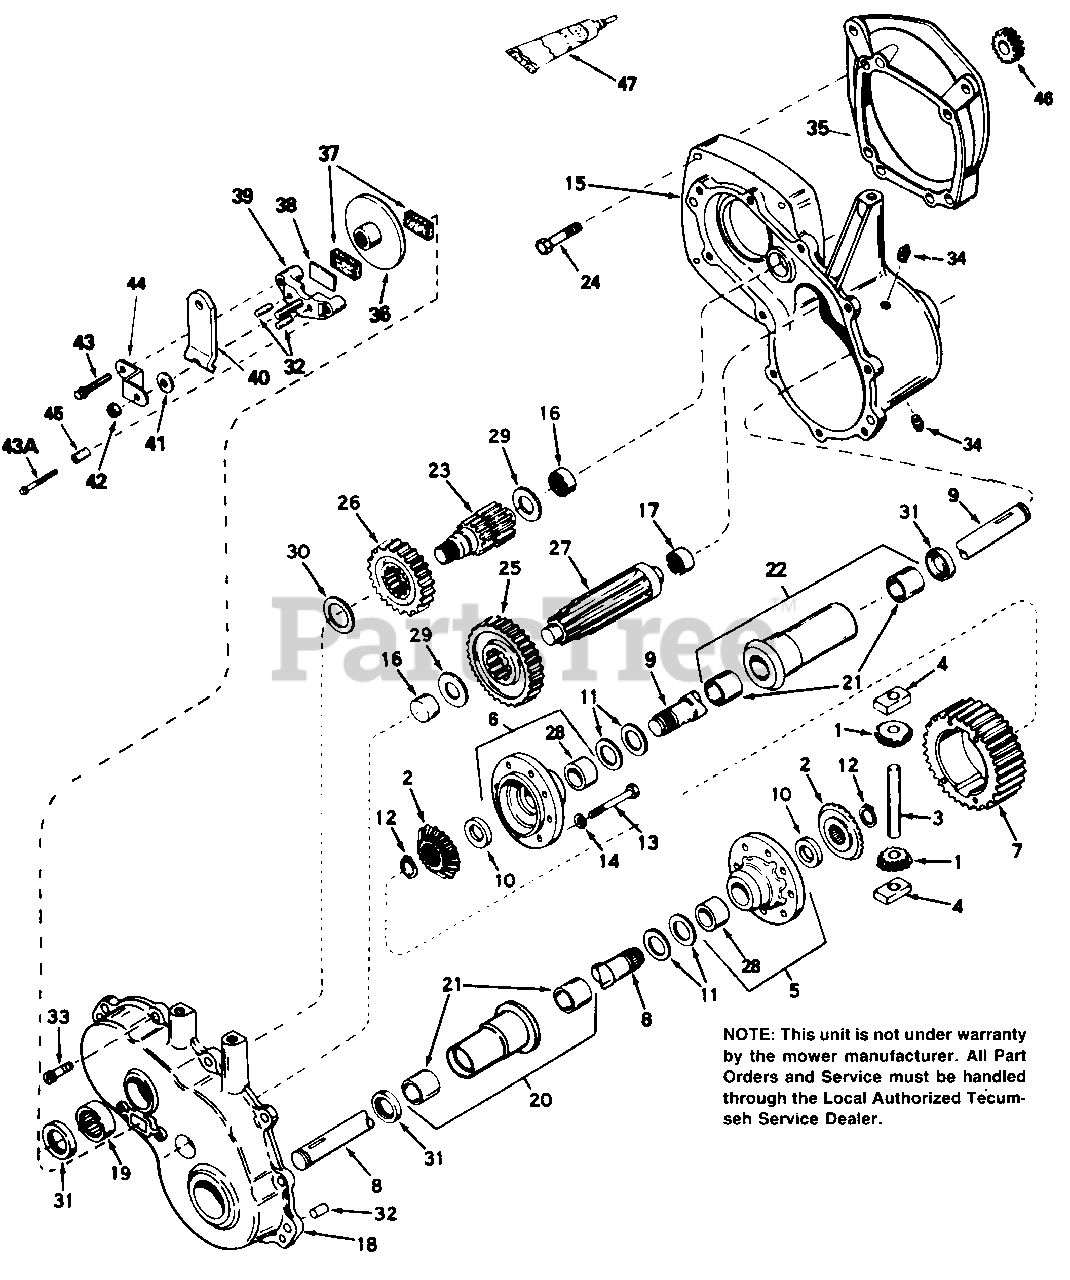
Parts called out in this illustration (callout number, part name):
1	Pinion, Bevel
2	Gear, Bevel
3	Pin, Drive
4	Block, Drive
5	Carrier Ass'y., Differential
6	Carrier Ass'y., Differential
7	Gear, Ring
8	Axle (13-1/16" Long)
9	Axle (19-1/8" Long)
10	Washer
11	Washer, Thrust
12	Ring, Snap
13	Screw, Hex Hd., 1/4-20 x 21/4
14	Lock Washer, 1/4"
15	Case Ass'y.
16	Bearing, Needle
17	Bearing, Needle
18	Cover Ass'y.
19	Bearing, Needle
20	Housing & Bushing Ass'y. (6-5/8" Long)
21	Bushing
22	Housing & Bushing Ass'y. (12-45/64" Long)
23	Shaft, Brake
24	Screw, Hex Hd., 3/8-16 x 2
25	Gear, Output
26	Gear, Idler
27	Shaft, Output
28	Bushing
29	Washer
30	Washer
31	Seal, Oil
32	Pin, Dowel
33	Screw, Hex Washer Hd. Thread Forming, 1/4-20 x 1
34	Plug, Pipe
35	Plate, Adapter
36	Disc, Brake
37	Pad, Brake
38	Plate, Brake Pad
39	Holder, Brake Pad
40	Lever, Brake
41	Washer, Flat
42	Lock Nut, 5/16-24
43	Screw, Flanged Hex Hd. [Thread Forming, 1/4-20 x 1-1/4
43A	Screw, Flanged Hex Hd. [Thread Forming, 1/4-20 x 2-1/4
44	Bracket
45	Spacer
46	Gear, Spur
47	Gasket Eliminator
